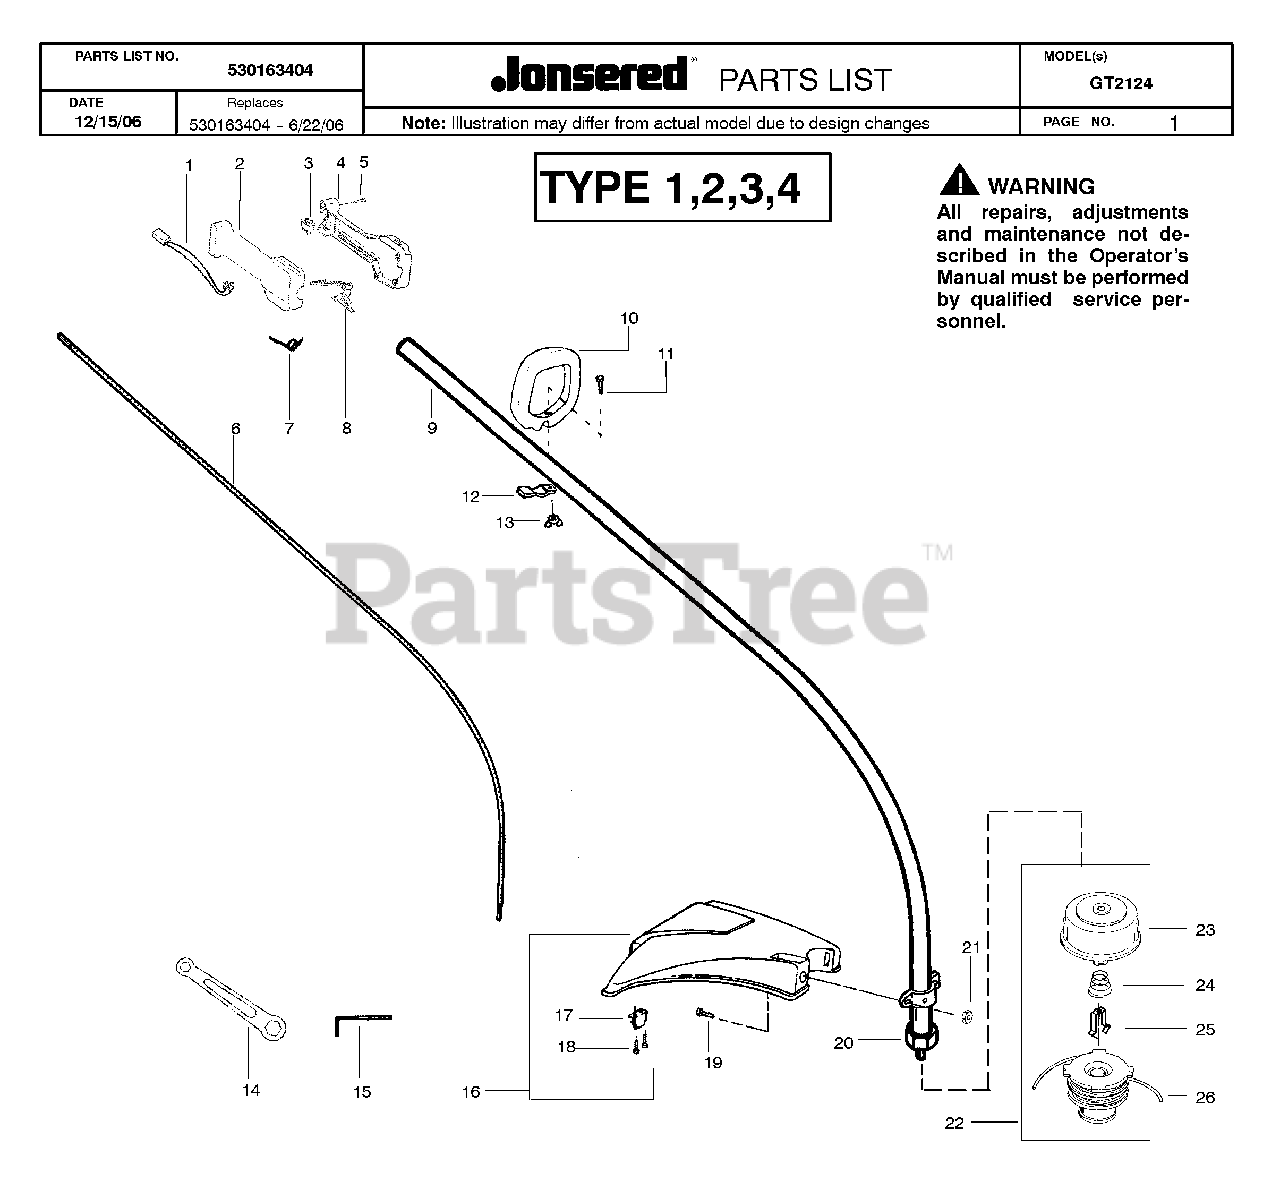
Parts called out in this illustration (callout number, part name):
5	SCREW-10-14 X 13/16 (PL
6	SHAFT-FLEX (48")
7	SPRING-LEVER RETURN
8	THROTTLE TRIGGER
10	HANDLE ASSY
11	BOLT, TYPE 2
13	WINGNUT, TYPE 2
15	HEX WRENCH 5/32
17	LINE CUTTER
19	BOLT, TYPE 2
23	KIT ASSY HUB W/ARBOR
